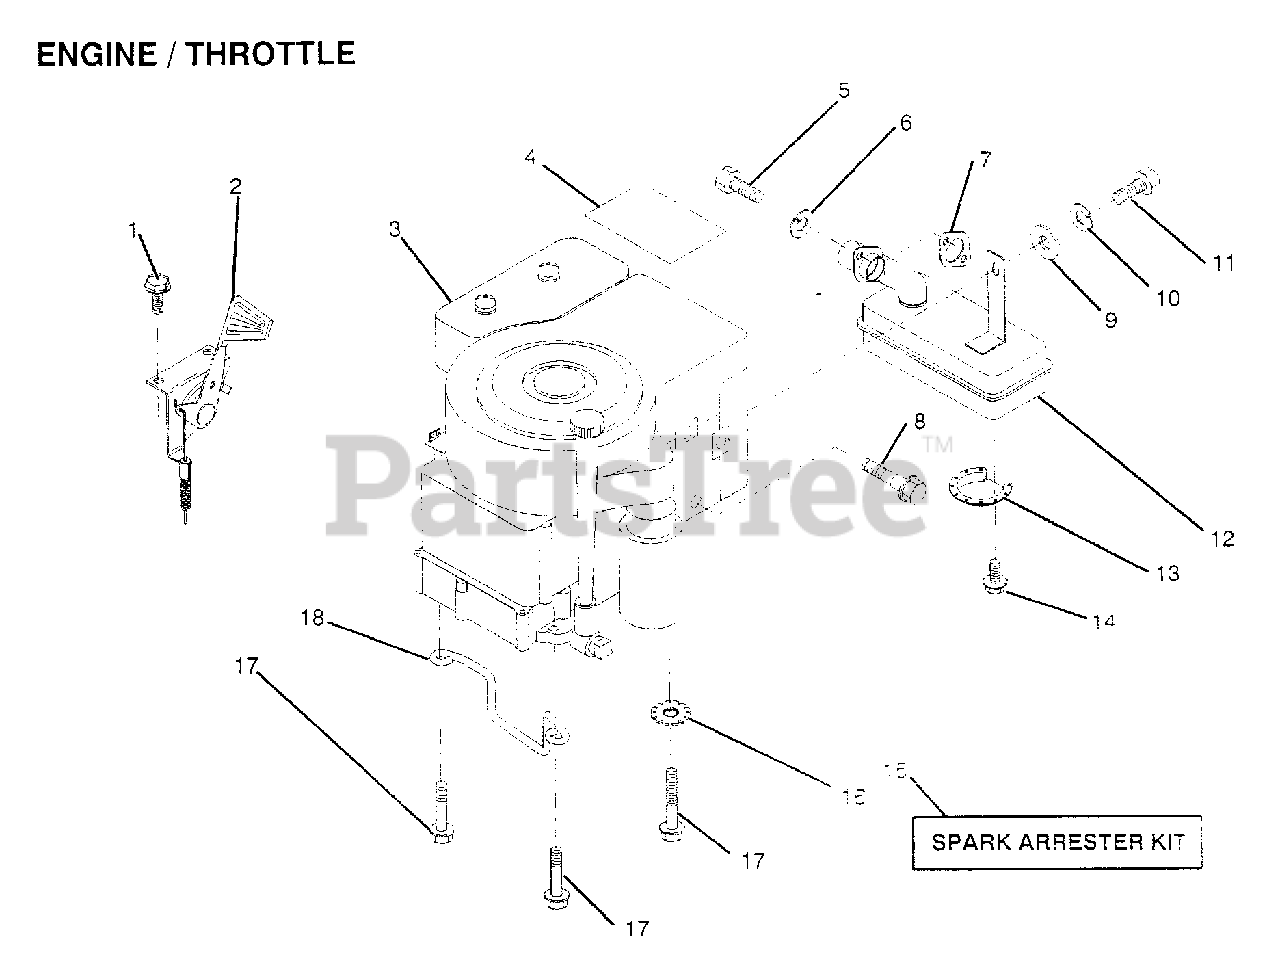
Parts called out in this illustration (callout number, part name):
1	SCREW
3	ENGINE BRIGGS AND STRATTON
5	SCREW
6	LOCKWASHER
8	BOLT T
10	LOCKWASHER
12	MUFFLER
13	DEFLECTOR.222573
16	LOCKWASHER
17	SCREW LT
18	"KEEPER,DR BELT GR"
